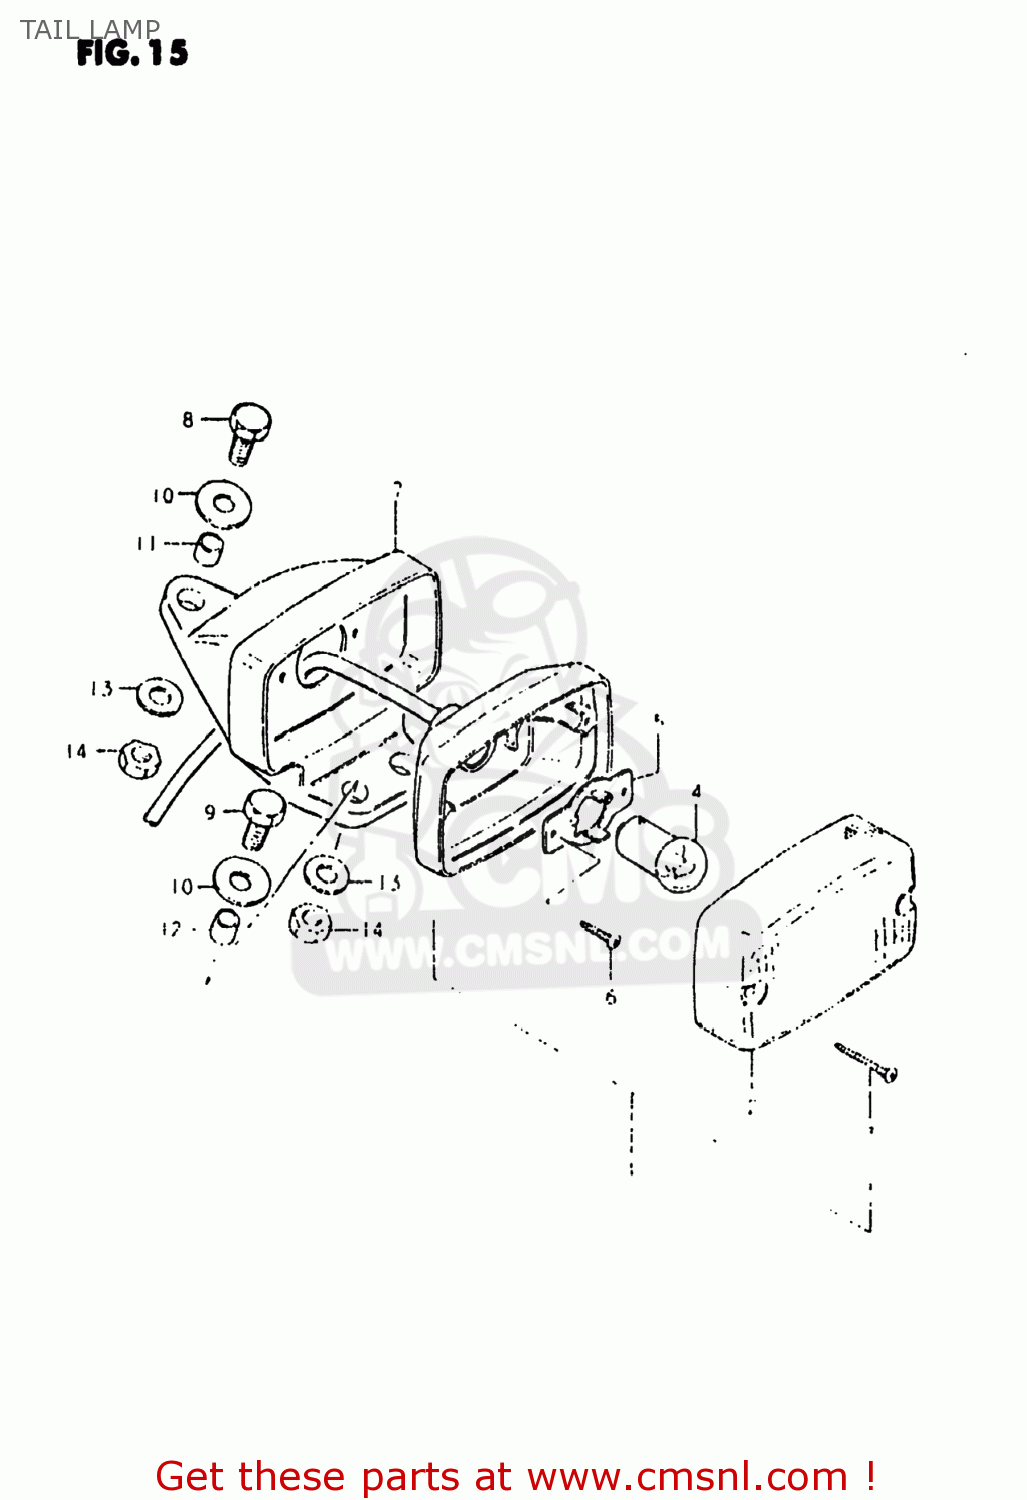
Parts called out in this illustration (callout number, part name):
1	LAMP UNIT,TAIL
2	LENS
3	SCREW
4	BULB(6V5W,TOKAI DENSO)
5	PLATE,TURN SIGNAL
6	SCREW
7	BRACKET
8	BOLT
9	BOLT, UPPER
10	WASHER (6.5X20X1.2)
11	SPACER (6.4X9X10.5)
12	SPACER (6.1X9X9)
13	WASHER
14	NUT
